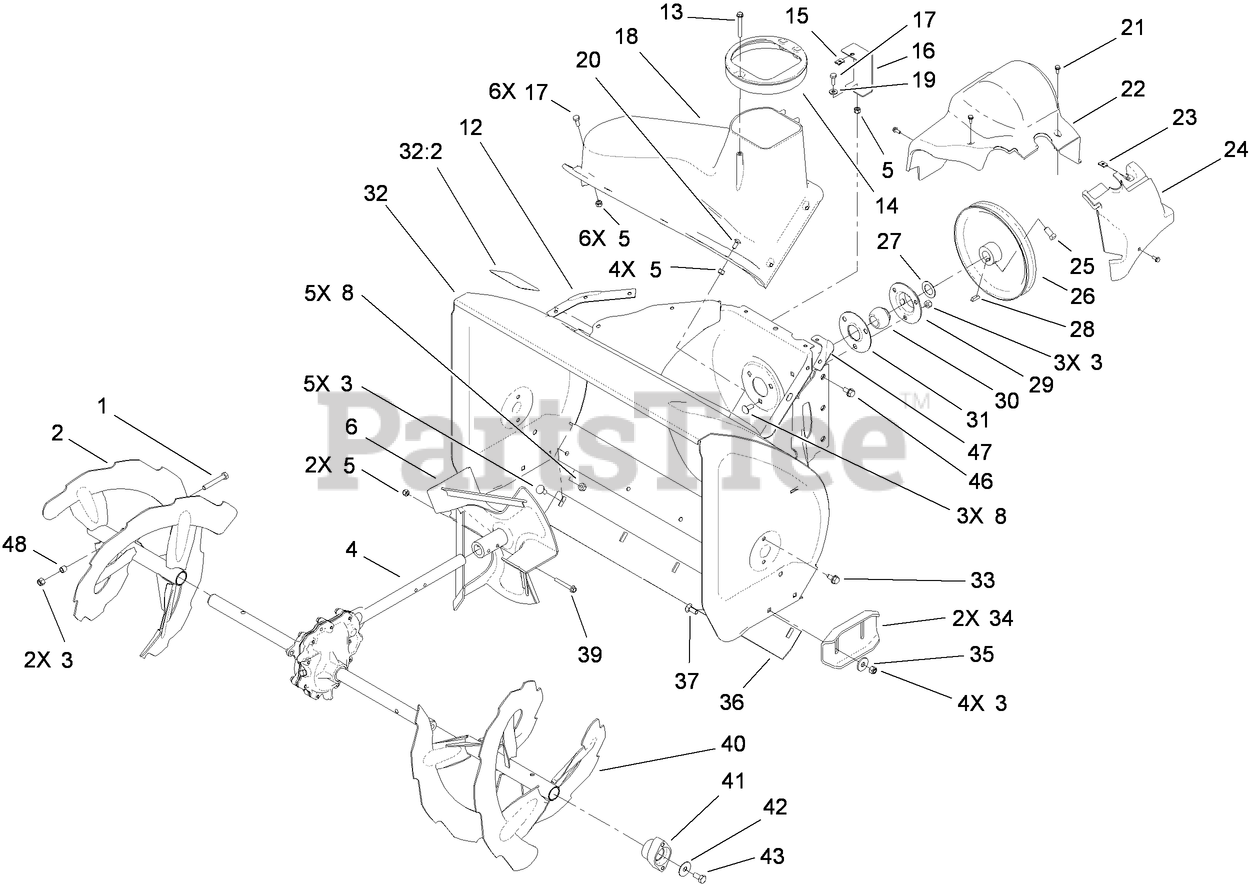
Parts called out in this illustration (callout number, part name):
1	SCREW-HH
2	RH AUGER ASM
3	NUT-LOCK, NI
5	NUT-LOCK, NI
6	IMPELLER ASM
8	SCREW-CARR
12	SEAL-FLANGE, COVER
13	SCREW-PLASTITE
14	GUIDE-CHUTE
15	NUT-SPEED
16	BRACKET-COVER, CLIP NUT
17	SCREW-HH
19	WASHER-FLAT
20	BOLT-CARR
21	SCREW-HWH
23	NUT-SPEED
24	COVER-EXTENSION, BELT
25	SCREW-SET, SQH
27	WASHER-THRUST
28	KEY-WOODRUFF
29	FLANGE-CUP, BEARING
30	BEARING-BALL
31	FLANGE-CUP, BEARING
32	HOUSING-AUGER, 28 INCH
32:2	DECAL-DANGER
33	SCREW-HWHTF
35	WASHER
36	SCRAPER-FIXED
37	SCREW-CARR
39	SCREW-HHF
40	LH AUGER ASM
41	BEARING-AUGER
42	WASHER
43	SCREW-HH
46	SCREW-HWHTF
48	SPACER
